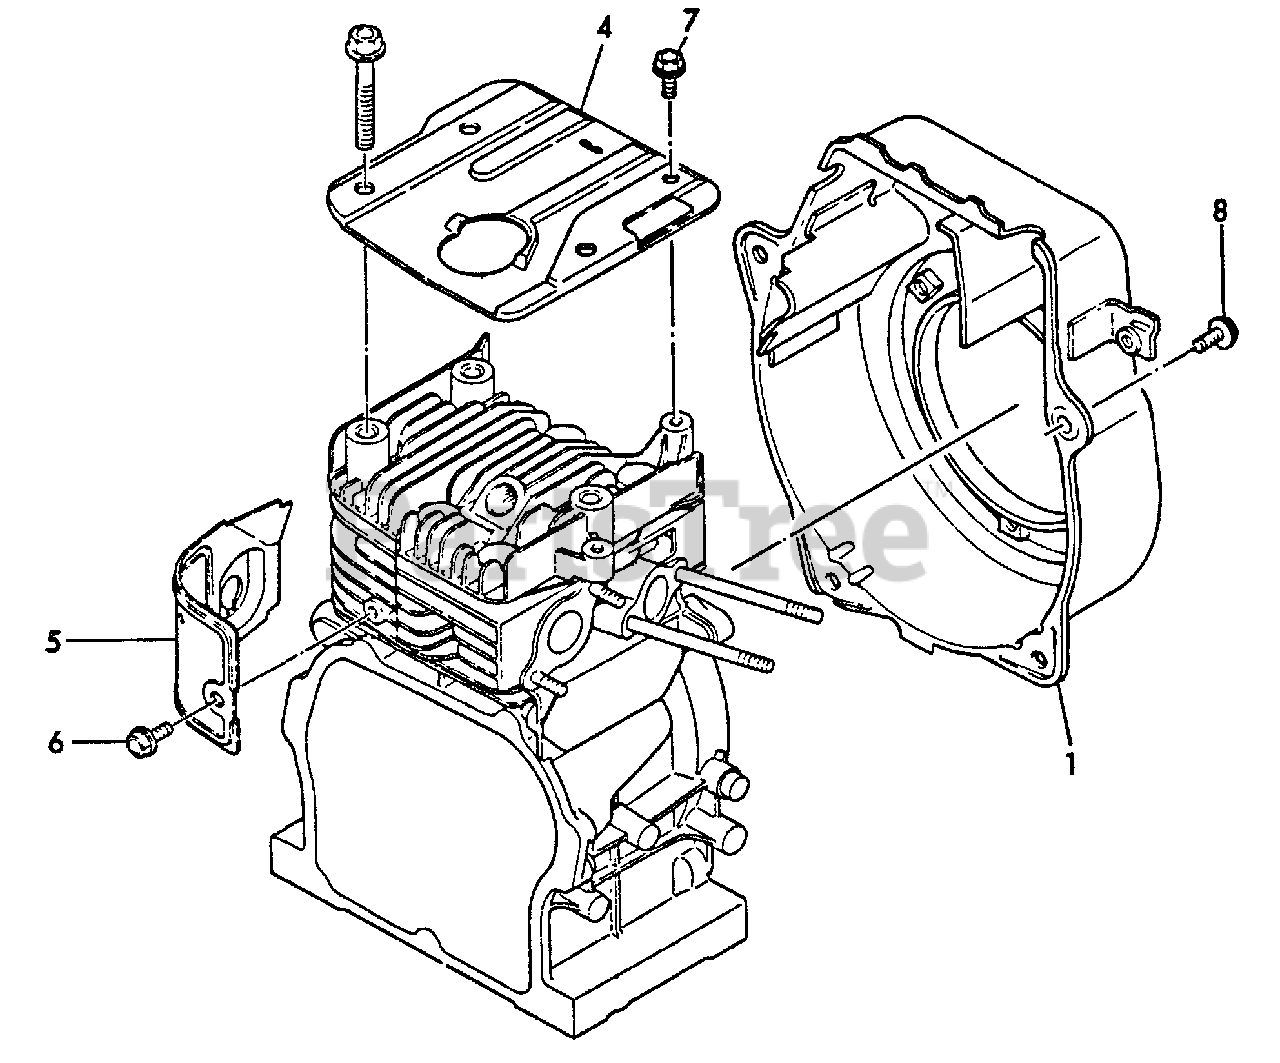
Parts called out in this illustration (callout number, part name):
1	COVER, FAN
4	COVER, CYLINDER HEAD
5	SHIELD, CYLINDER
6	BOLT - 6X8 -- PLATED
7	BOLT - 6X8 -- PLATED
8	BOLT - 6X8 -- PLATED
